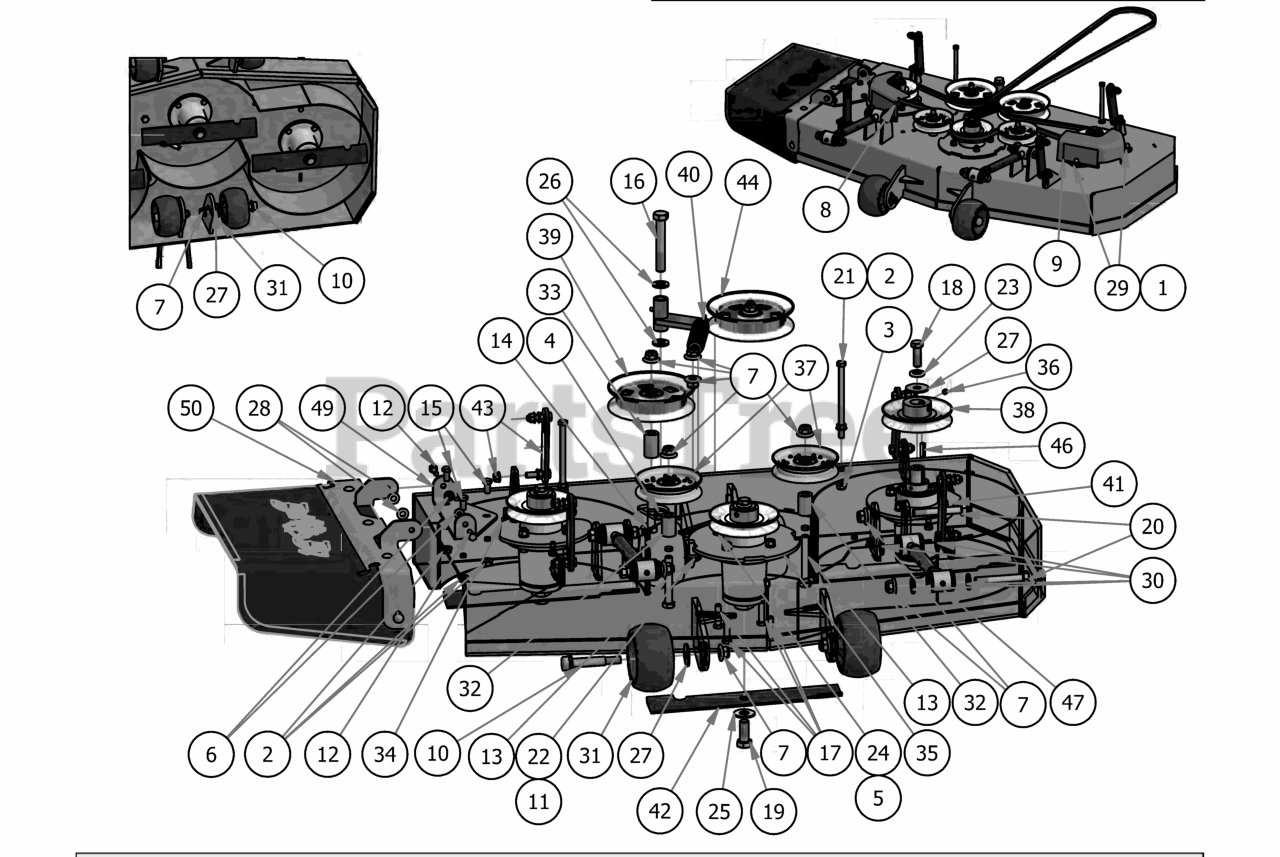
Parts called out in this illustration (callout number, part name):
1	Acorn nut-pulley Cover
2	3/8" Flange Nut
3	3/8" Nylock Flange Nut
4	5/8-11 Nylon Insert Jam Half Nut
5	3/8" Hex Nut
6	5/16" Nylon Flange Nut
7	1/2-13 Nylon Flange Nut
8	pulley cover chute side
9	pulley cover non-chute side
10	Deck Wheel Bolt
11	1/2 x 2" Carriage Bolt
12	5/16-18 x 1 GR 5 Hex Bolt Zinc
13	1/2 x 3 1/2 Flange Bolt Grade 8
14	1/2" x 4" Bolt (Grade 8)
15	3/8" x 3/4" Hex Bolt
16	5/8" x 4" Hex Bolt
17	3/8 x 1.5" Bolt
18	1/2"-20 x 1 1/2 - Grade 5 Fine Thread Bolt
19	5/8 x 1 1/2 Grade 8 Hex Bolt (Fine)
20	1/2-13 x 3 1/2 GR 5 Hex Bolt
21	3/8-16 x 5 1/2 Hex Bolt
22	.517 Square Hole Round Washer
23	1/2" Lock Washer Zinc
24	3/8" Lock Washer
25	5/8'' Flat Washer
26	.630 ID Plastic Washer
27	1/2" Belleville Washer
28	.360 ID Plastic Washer
29	.360 ID Plastic Washer-Black
30	.505 Nylon Spacer
31	Deck Wheel
32	.502 ID X .750 OD X 1.500 Long Spacer
33	1 3/4" Pulley Spacer
34	42&48 Deck Spindle Support Plate
35	Deck Spindle Support Plate
36	5/16 Set Screw
37	4 3/4 Idler Pulley - ABFI-76
38	5" Spindle Deck Pulley
39	5-3/4 Idler Pulley
40	Deck Idler Spring
41	Spindle Assembly
42	42'' High lift Blade
43	Deck Hanger Assembly
44	2017 54"/48" Deck Idler Assembly
46	1/4" x 1" Key
47	2018 Maverick Turnbuckle (Top Link)
48	42" Deck Shell
49	Discharge Chute Hanger (deck mounted)
50	ZT Chute Assembly
